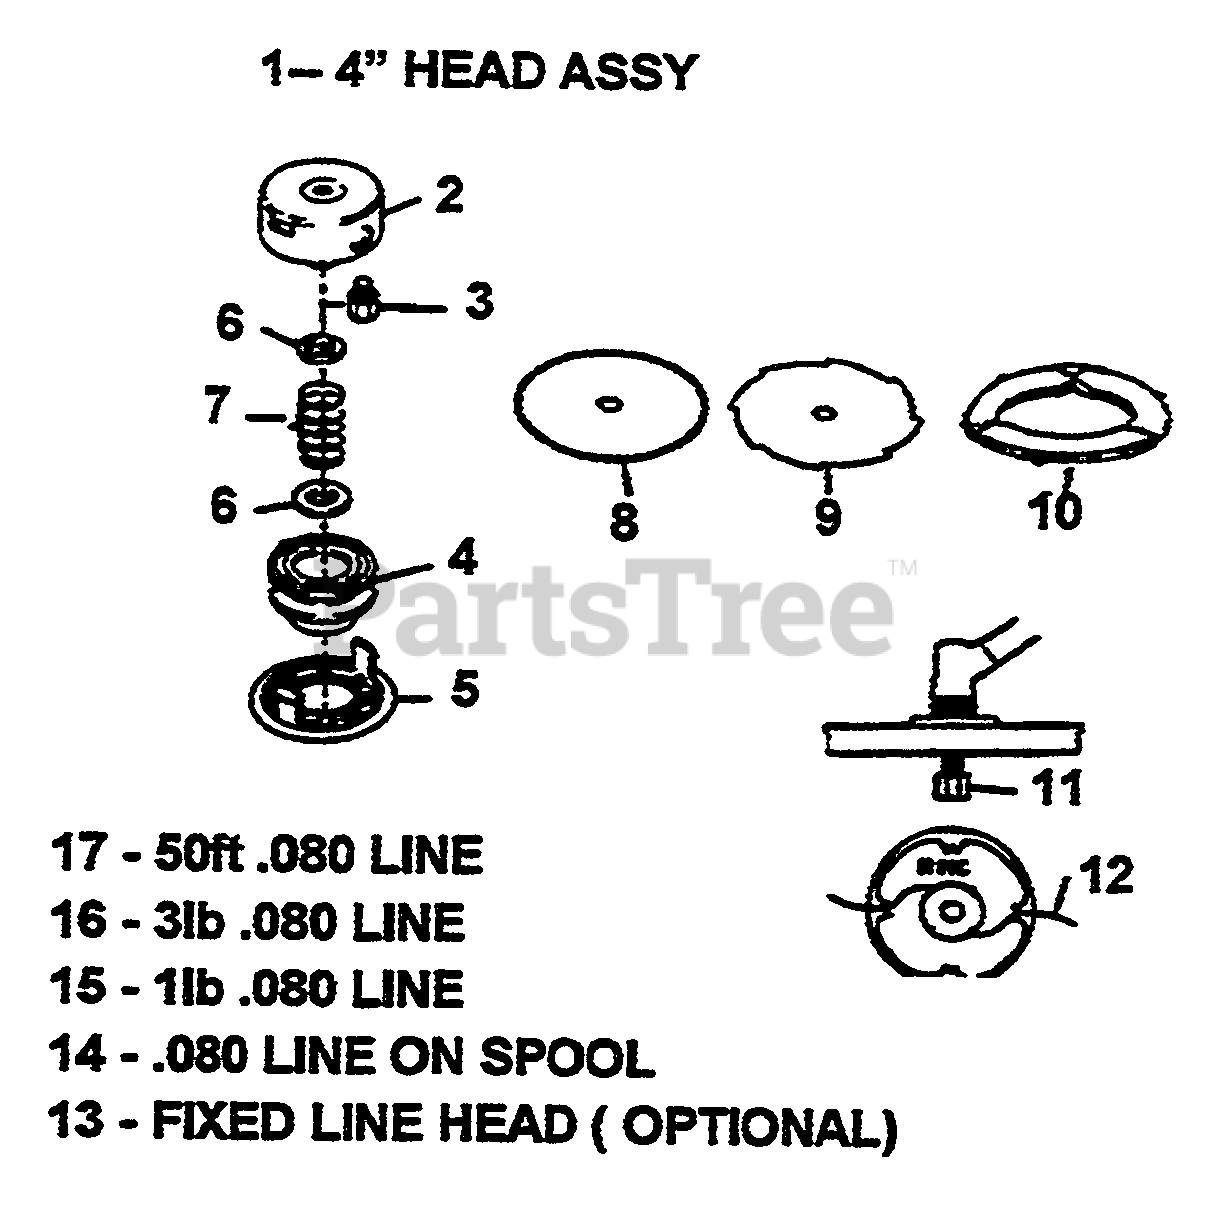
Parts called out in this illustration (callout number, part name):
1	4" HEAD ASSY
3	ARBOR BOLT
4	SPOOL
6	PLATE, SPRING
7	SPRING
8	9" SAW BLADE
9	9" BRUSH BLADE
10	BLADE COVER
11	ARBOR BOLT
12	.105 LINE, 20" STRIPS
13	FIXED LINE HEAD
14	SPOOL & LINE
15	1lb .080 LINE
16	31b .080 LINE
17	50ft.080 LINE
